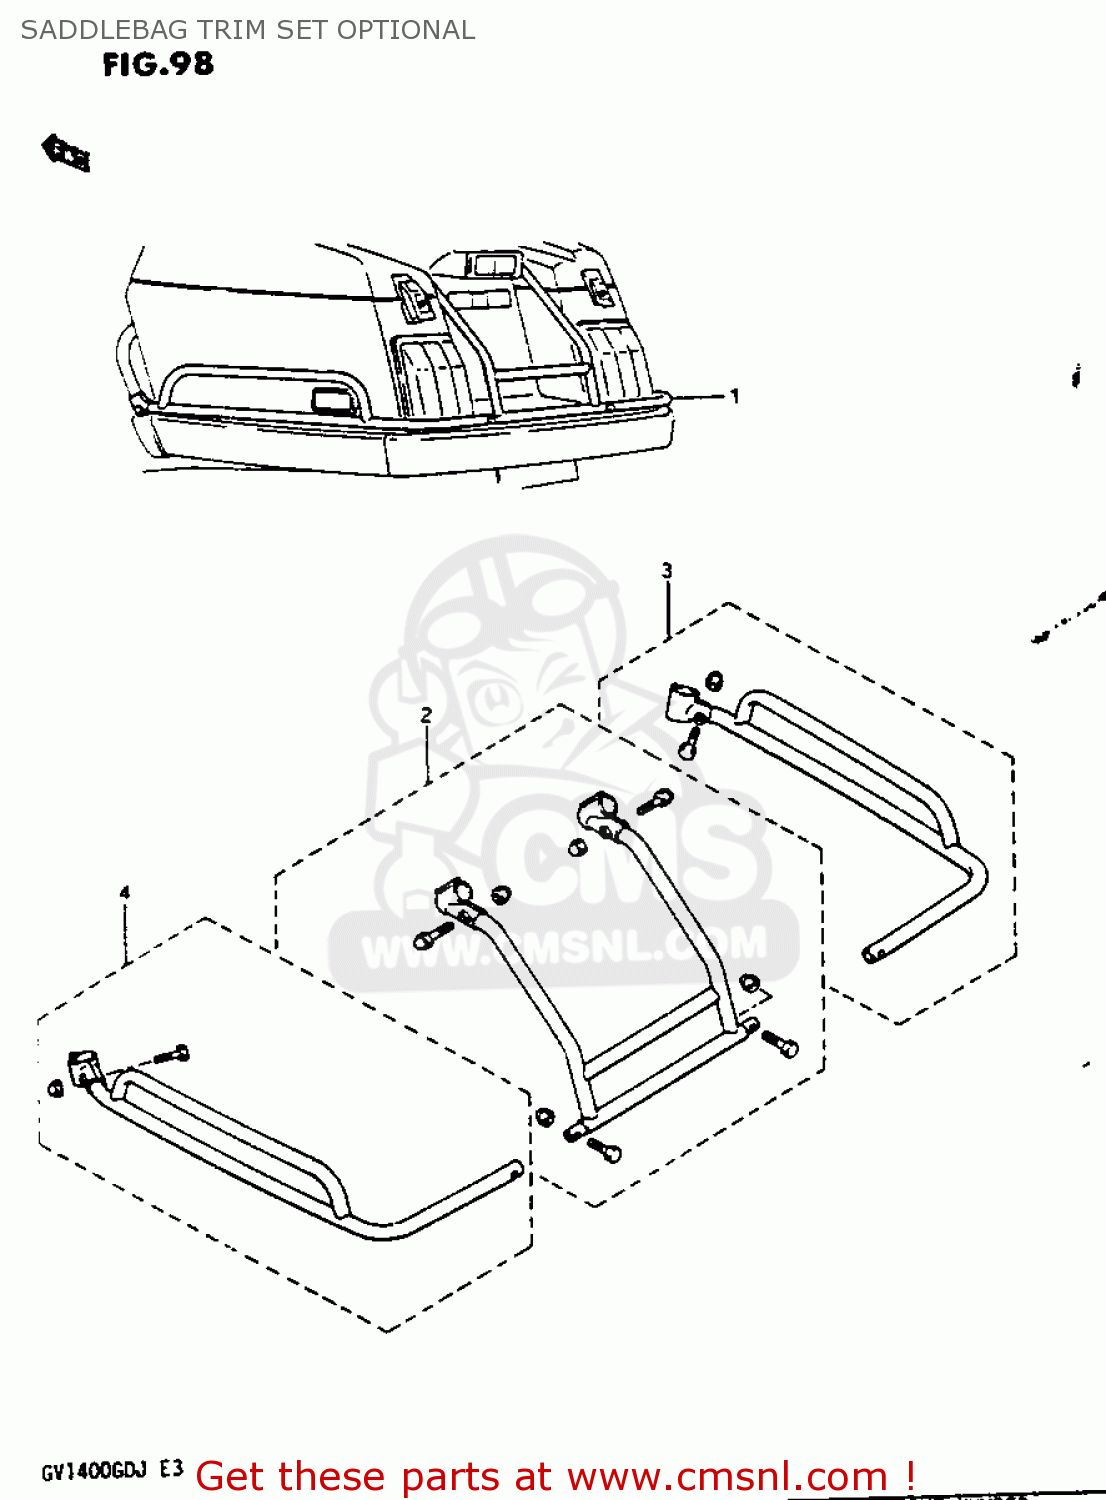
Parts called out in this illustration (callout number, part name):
1	TRIM SET, SADDLEBAG
2	TRIM, SADDLEBAG CENTER
3	TRIM, SADDLEBAG RH
4	TRIM, SADDLEBAG LH
